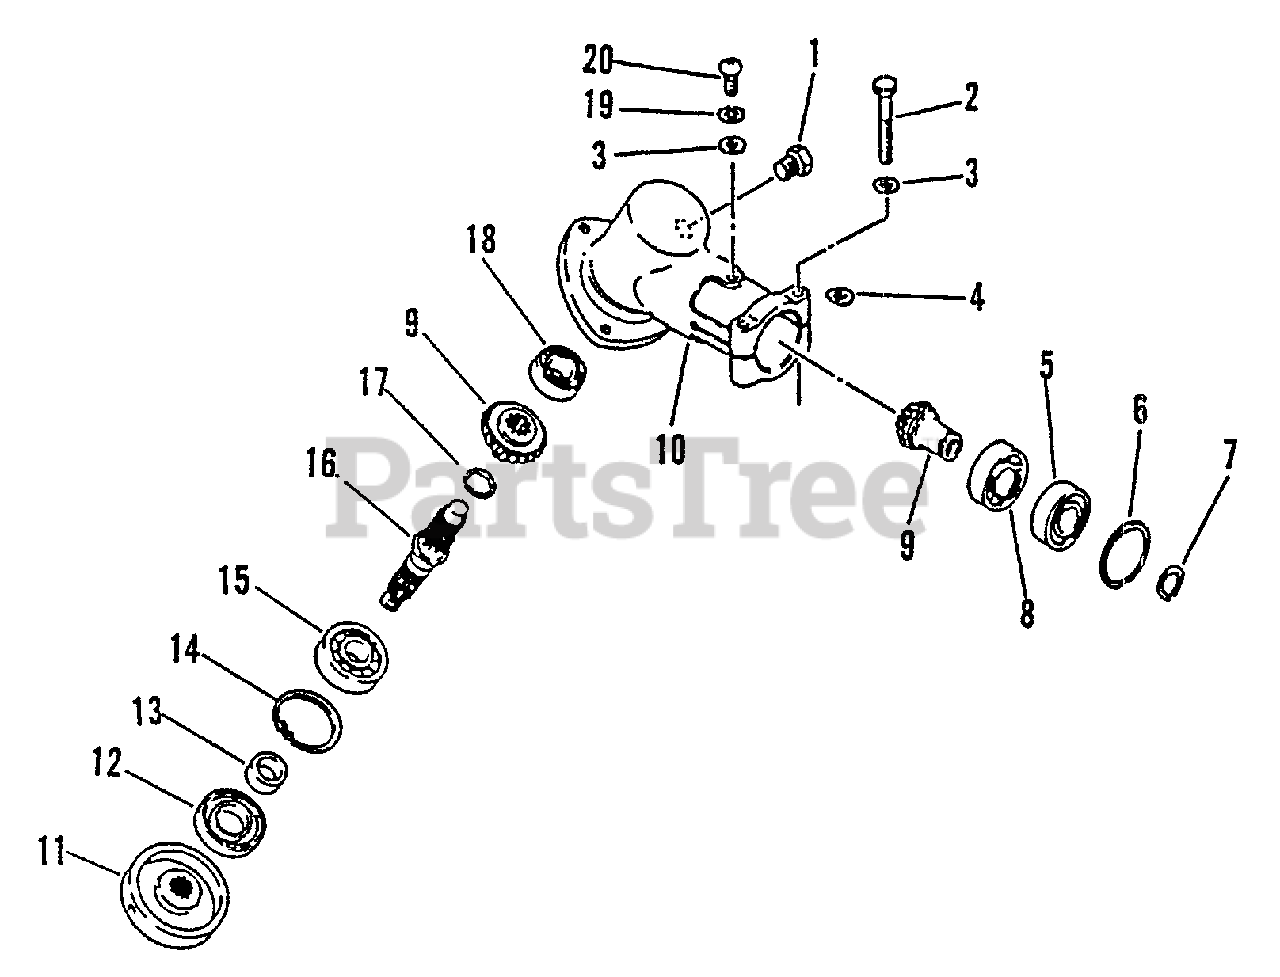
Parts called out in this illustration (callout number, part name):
1	BOLT 8×8 SP
2	BOLT 5×35 SP
3	WASHER, FLAT 5.5×10×0.8
5	BEARING, BALL 6900Z
6	RING, SNAP Ø22
7	RING, SNAP Ø12
8	BEARING, BALL 6900
9	GEAR SET
10	HOUSING, GEAR CASE
11	PLATE, ADAPTOR - UPPER
12	SEAL, OIL 22
13	SPACER 11.8×15×9
14	RING, SNAP Ø32
15	BEARING, BALL - 6201 C3
16	SHAFT, GEAR
17	RING, SNAP Ø10
18	BEARING, BALL 609
19	WASHER, SPRING 5
20	SCREW 5×10
